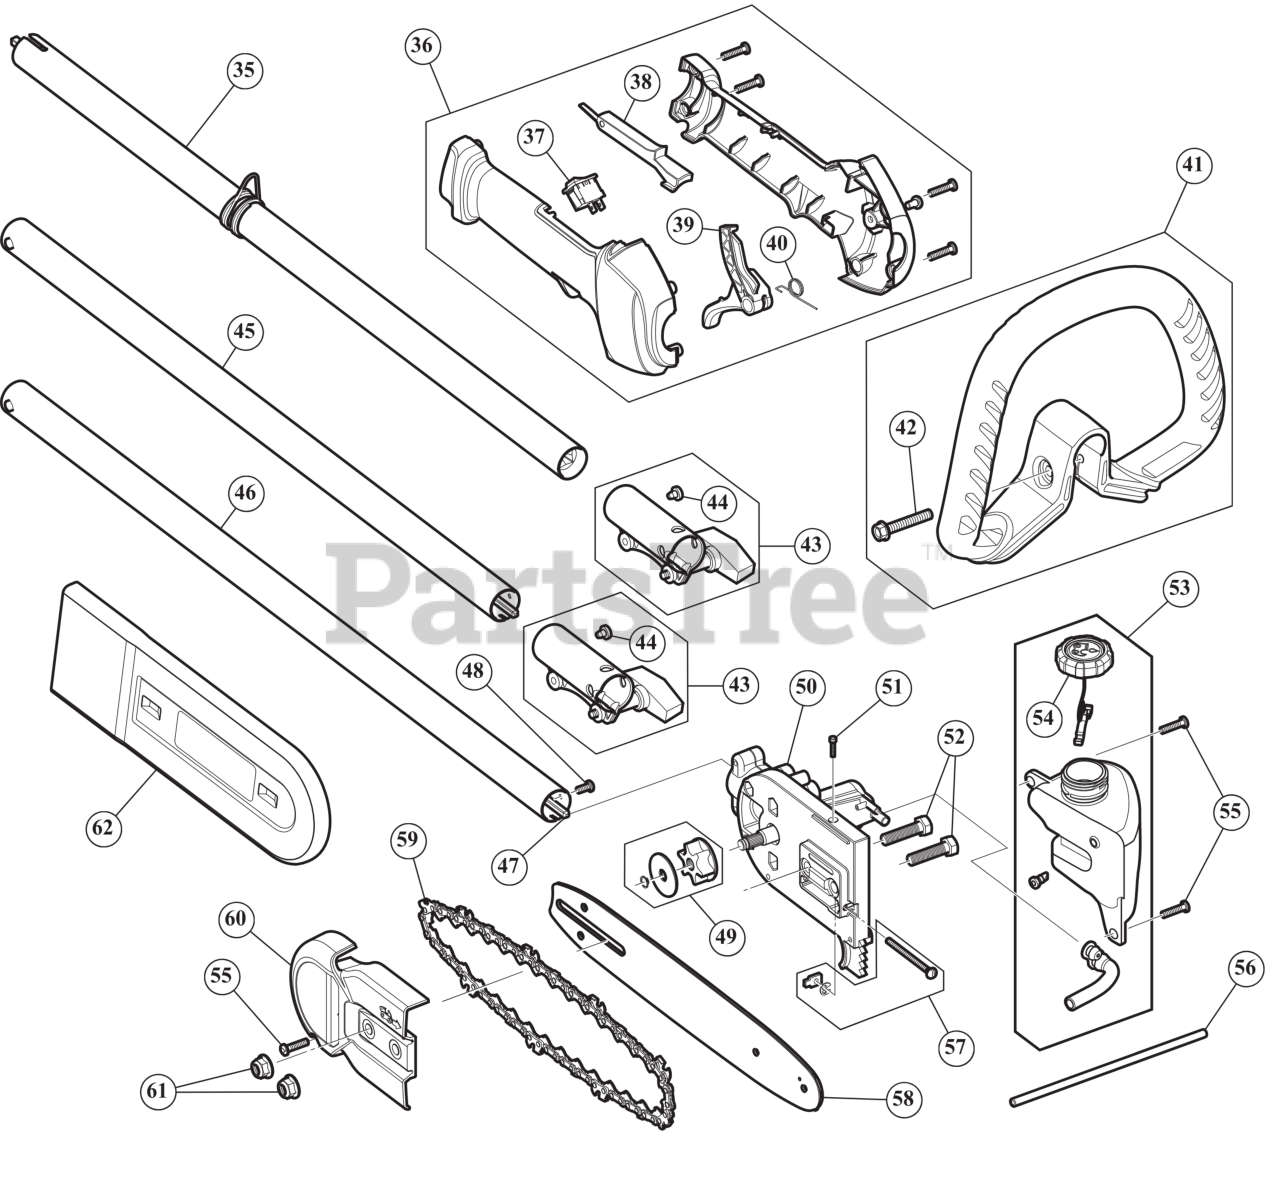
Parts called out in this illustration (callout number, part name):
35	BOOM ASSEMBLY UPR
36	THROTTLE GRIP ASSEMBLY
37	SW, MOMENTARY ON/O
38	LEVER LOCK OUT
39	THROTTLE TRIGGER
40	TRIGGER SPRING
41	HANDLE ASSEMBLY
42	BOLT 1/4-20X1 1/2
43	COUPLER ASSEMBLY
44	SCREW, 10-32X.250 TA
45	EXTENSION BOOM
46	LOWER SHAFT HOUSING
47	FLEXIBLE DRIVE SHAFT
48	SCREW 1/4-20 X.500
49	SPROCKET ASSEMBLY
50	GEAR BOX ASSEMBLY
51	SCREW 4X40X.50
52	SCREW 5/16-18 x 1.25 GR5
53	OIL TANK
54	OIL CAP
55	SCREW, #8-16X.750 PH
56	OIL LINE
57	CHAIN TENSION HDW
58	BAR 10"
59	CHAIN 10"
60	GUARD CHAIN
61	FLANGE LOCK NUT 5/16-18
62	SCABBARD
